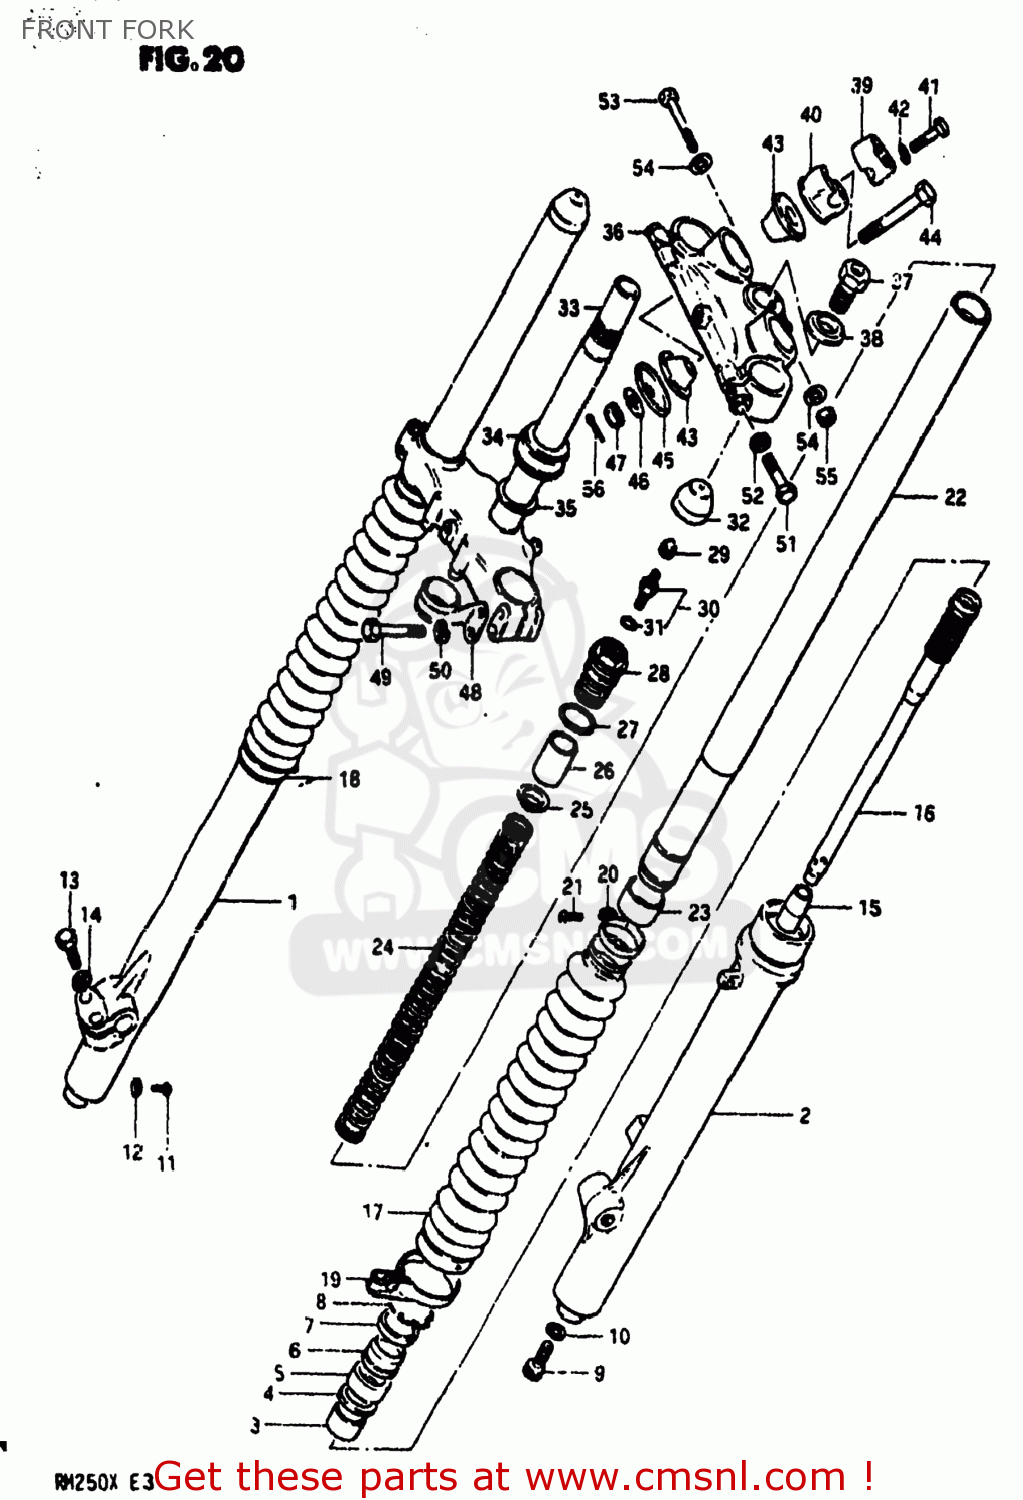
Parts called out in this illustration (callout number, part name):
1	TUBE,OUTER,RIGHT
2	TUBE,OUTER,LEFT
3	METAL,SLIDE
4	WASHER(40X50X2.3)
5	SEAL,OIL
6	SEAL,DUST
7	CASE,DUST SEAL
8	RING,STOPPER
9	BOLT,CYLINDER
10	GASKET,CYLINDER (NAS)
11	SCREW
12	GASKET,DRAIN,PLUG (NAS)
13	BOLT (8X30)
14	WASHER,LOCK,8.
15	PIECE,OIL LOCK
16	CYLINDER,FRONT FORK
17	BOOT
18	BAND,FRONT FORK COVER BOOT
19	BAND,FRONT FORK COVER BOOT
20	BAND,BOOT
21	SCREW 4X10
22	TUBE,FORK,INNER
23	PISTON
24	SPRING,FRONT FORK
25	GUIDE
26	SPACER,FRONT FORK SPRING
27	O RING
28	CAP,FORK INNER TUBE
29	CAP,VALVE AIR
30	VALVE
31	O RING
32	CAP
33	STEM,STEERING
34	BEARING
35	WASHER,THRUST
36	HEAD,STEERING STEM
37	BOLT
38	WASHER
39	HOLDER,HANDLEBAR
40	HOLDER,HANDLEBAR,LOWER
41	BOLT
42	WASHER,LOCK,8.
43	CUSHION,HANDLE HOLDER
44	BOLT,HANDLE HOLDER
45	COVER,HANDLEBAR HOLDER
46	WASHER,HANDLEBAR HOLDER
47	NUT
48	CLIP,CABLE
49	BOLT 8X45
50	WASHER,LOCK,8.
51	BOLT
52	WASHER,LOCK,8.
53	BOLT 8X50
54	WASHER
55	NUT
56	PIN 20X20
